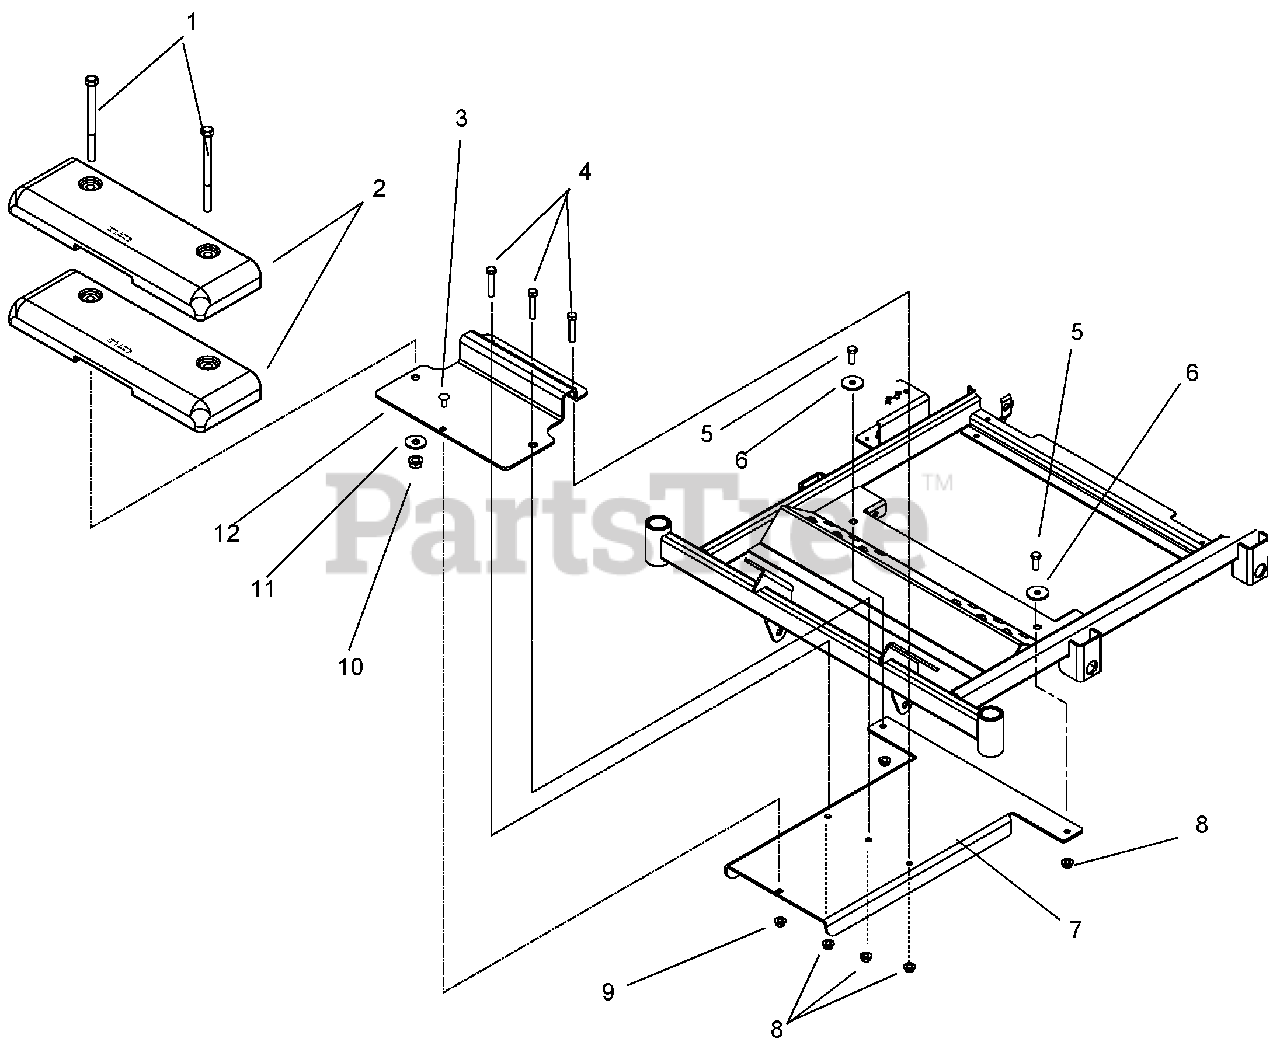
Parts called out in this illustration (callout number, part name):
1	@BLT-HEX .50-13X5.00 GR5 YWZC
2	WEIGHT, CAST IRON
3	@BLT-RDHDSQNK .31-18X.75 G5YZ
4	@BLT-HEX .38-16X2.00 GR5 YWZC
5	@BLT-HEX .38-16X1.00 GR5 YWZC
6	WSHR-FL-STL .390X1.5X.125 YWZC
7	BRACKET, WEIGHT MOUNT
8	@NUT-LK-NYL-FLG .38-16 YWZC
9	@NUT-LK-NYL-FLG .31-18 YWZC
10	@NUT-LK-TOP-FLG .50-13 YWZC
11	WSHR-FL-STL.511X1.441X.125 YWZ
12	BRACKET, BAGGER AXLE MOUNT
